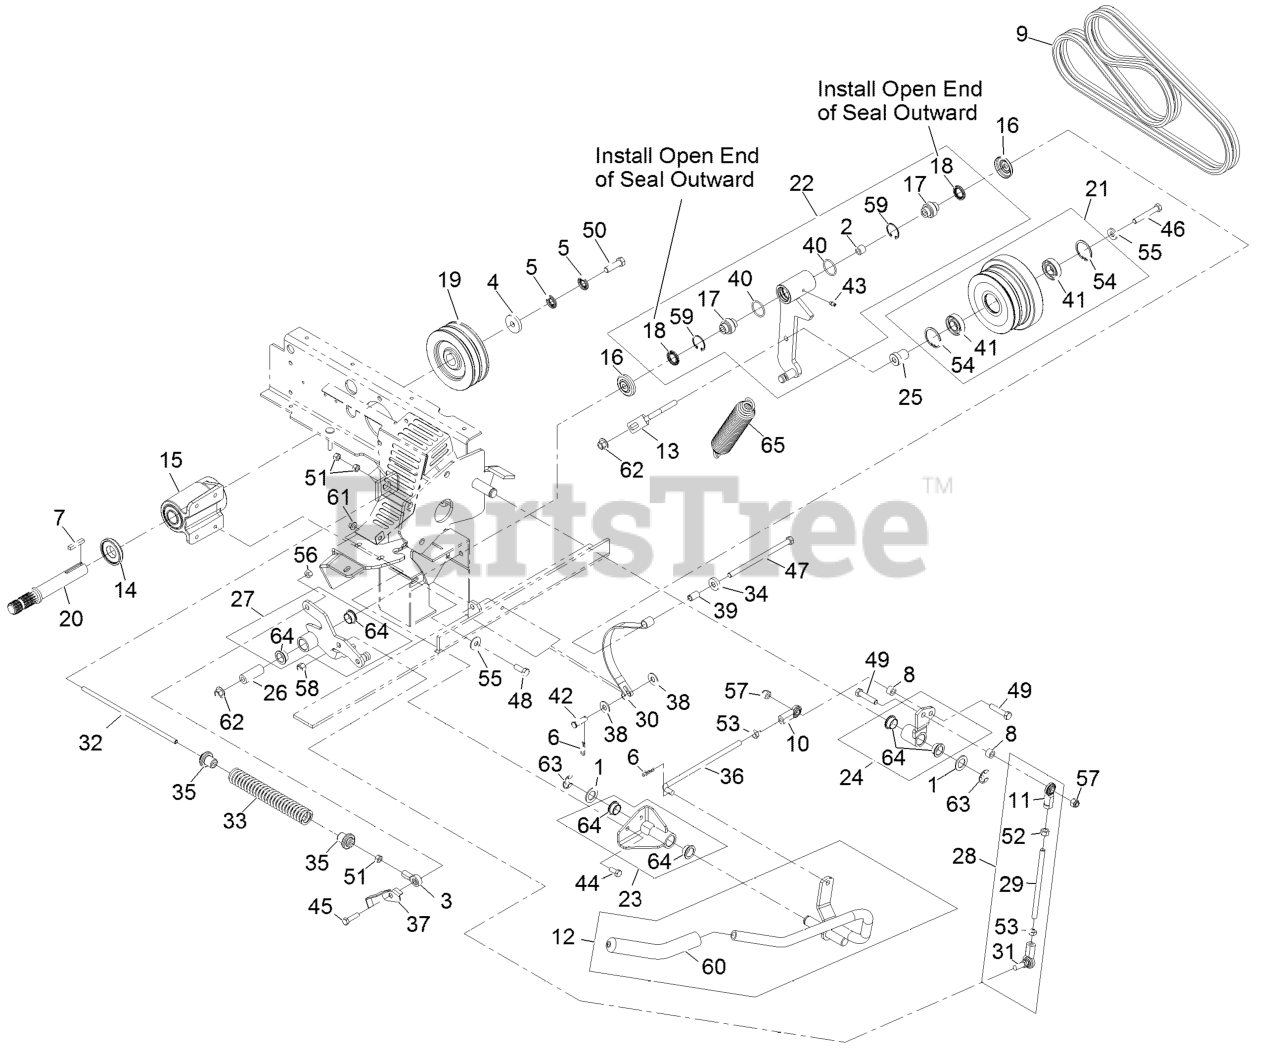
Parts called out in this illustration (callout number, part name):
2	BUSHING-LEVER, LIFT
3	BALLJOINT-RH
4	WASHER-CLUTCH
5	WASHER-SPRING
6	PIN-COTTER
7	KEY-SQUARE
9	BELTS-MATCHED PAIR
10	JOINT-BALL, END
11	JOINT-BALL END, LH
12	PTO HANDLE ASM
13	GUIDE-BELT
14	SPACER-GUARD, BOTTOM
16	GUARD-TOP
17	BEARING-SPHERICAL
18	SEAL-LIP, SINGLE
20	SHAFT-JACK
21	IDLER SHEAVE ASM
22	IDLER PIVOT ASM
23	PIVOT ASM
24	ARM ASM
25	SPACER-IDLER
26	BUSHING
27	ARM ASM
28	CLUTCH LINK ASM
29	ROD-LINKAGE
30	BAND-BRAKE
31	BALLJOINT-RH
32	LINKAGE-ROD, PTO BRAKE
33	SPRING-BRAKE
34	SPACER
35	BUSHING-SPRING
36	LINK-HANDLE
37	SWITCH-FLAG
38	WASHER-FLAT
41	BEARING-BALL
42	PIN-CLEVIS
43	FITTING-GREASE
44	SCREW-HH
45	SCREW-HH
46	BOLT-CARR
47	SCREW-HH
48	SCREW-HH
49	SCREW-HH
50	SCREW-HH
51	NUT-HEX
52	NUT-HEX, LH
53	NUT-HEX
54	RING-RETAINING
55	WASHER-BELLEVILLE
56	NUT-LOCK, NI
57	NUT-LOCK, NI
58	NUT-LOCK
59	RING-SNAP
60	GRIP-LEVER, CONTROL
64	BUSHING-BRONZE
65	SPRING-EXTENSION
